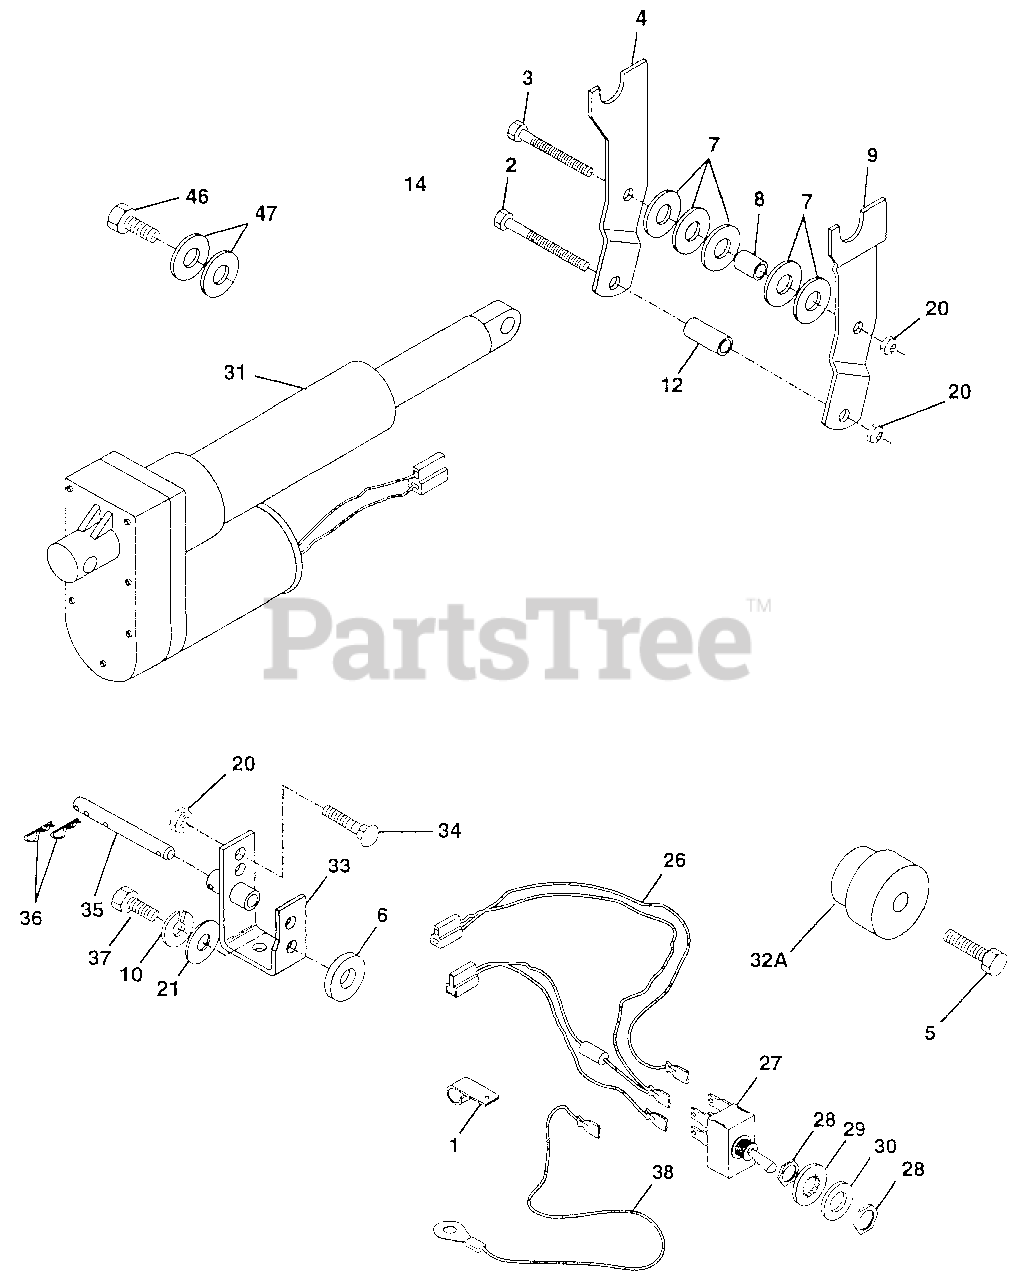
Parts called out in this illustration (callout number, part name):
1	Clip, Insulated
2	Bolt, Hex 3/8-16 x 2-1/4 Grade 5
3	Bolt, Hex 3/8-16 x 1-3/4 Grade 5
4	Bracket, Lift L.H.
5	Bolt, Hex 3/8-16 x 1-3/8
6	Washer 13/32 x 7/8 x 7 Ga.
7	Washer 17/32 x 1-1/2 x 10 Ga.
8	Tube .384 x 1/2 x 15/16
9	Bracket, Lift R.H.
10	Washer, Lock
12	Bushing .384 x 1/2 x 1-1/4
14	Spring, Retainer
20	Locknut 3/8-16
21	Washer 13/32 x 7/8 x 16 Ga.
26	Harness, Lift Kit
27	Switch, Lift
28	Nut, Switch
29	Washer, Lock Int. Tooth
30	Washer 15/32 x 3/4 x 16 Ga.
31	Electric, Actuator
32A	Hub, Lever Lift (Splined)
33	Bracket, Assembly Actuator, Gear Drive
34	Bolt, Carriage 3/8-16 x 1
35	Pin, Actuator
36	Spring, Retainer
37	Bolt, Hex 3/8-16 x 1
38	Wire, Ground
46	Bolt, Hex 5/16-18 x 1-1/4
47	Washer 11/32 x 1-1/2 x 10 Ga.
